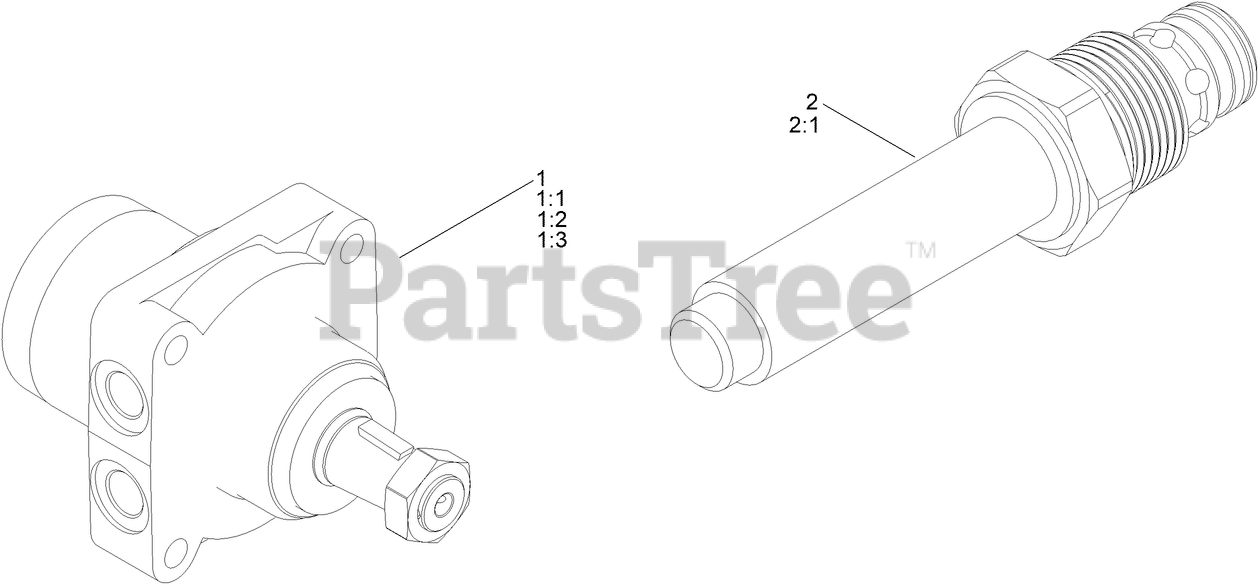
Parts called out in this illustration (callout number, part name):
1	HYD MOTOR ASM
1:1	KEY-WOODRUFF
1:2	SEAL KIT
1:3	NUT-LOCK
2	CARTRIDGE-RELIEF
2:1	SEAL KIT
